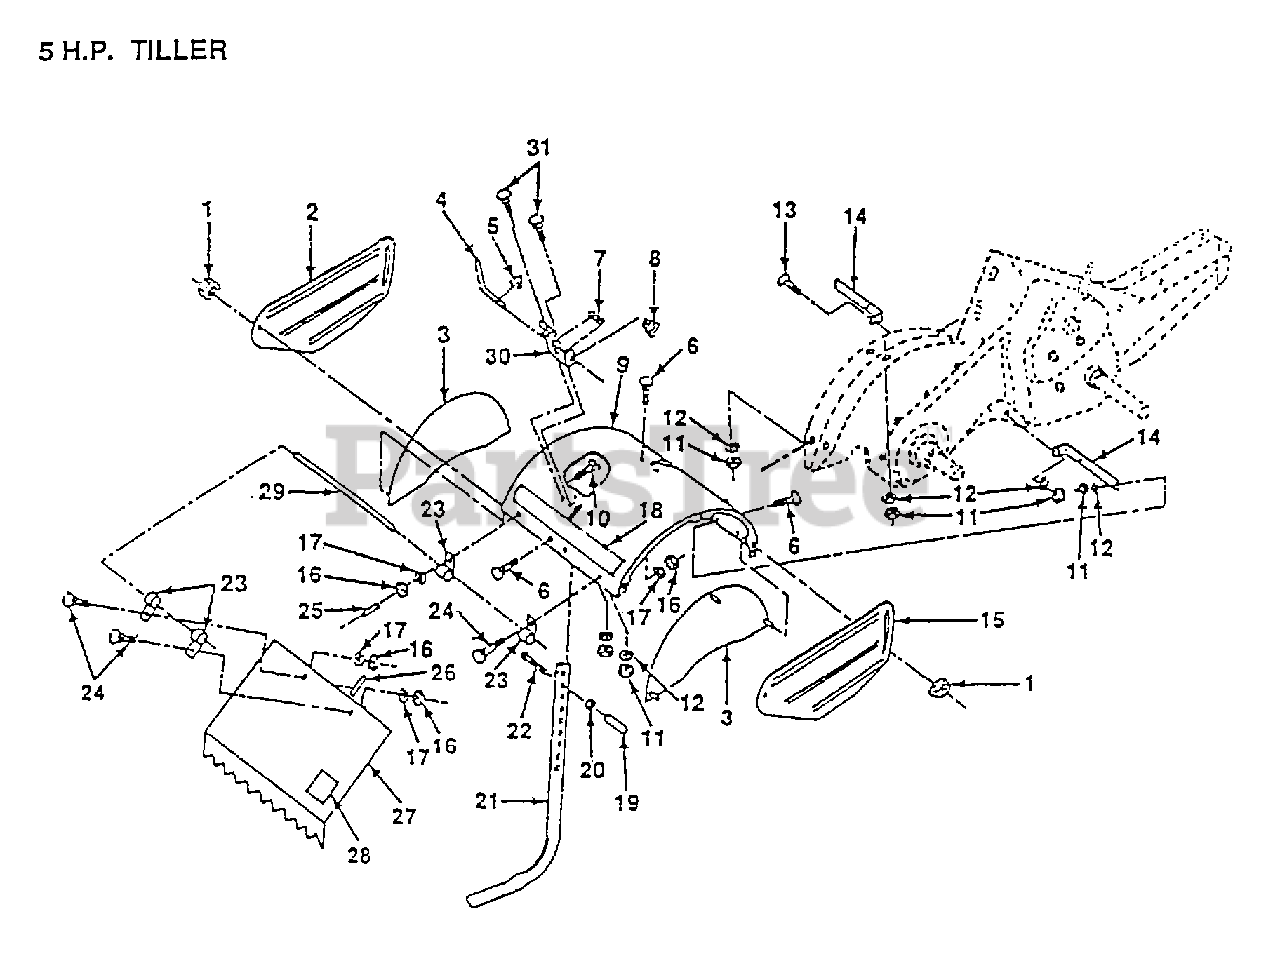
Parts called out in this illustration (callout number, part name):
1	NUT
4	STAKE PIN TI
5	KLIP RING TI
6	BOLT
7	SPRING TI
8	SPRING CRT
9	SHLD TINE
10	BOLT
11	LOCKWASHER
12	NUT.HEX.5/16-18
13	BOLT
14	BRKT SHIELD TINE
17	LOCKWASHER
18	DECAL, TINE SHIELD
19	GRIP CRT
20	NUT.HEX.3/8-16UNC
22	BOLT
23	HINGE CRT
24	BOLT
25	VINYL CAP TI
26	PAD IDLER TI
29	PIN HINGE
30	LATCH BRACKET TI
31	BOLT CRT
